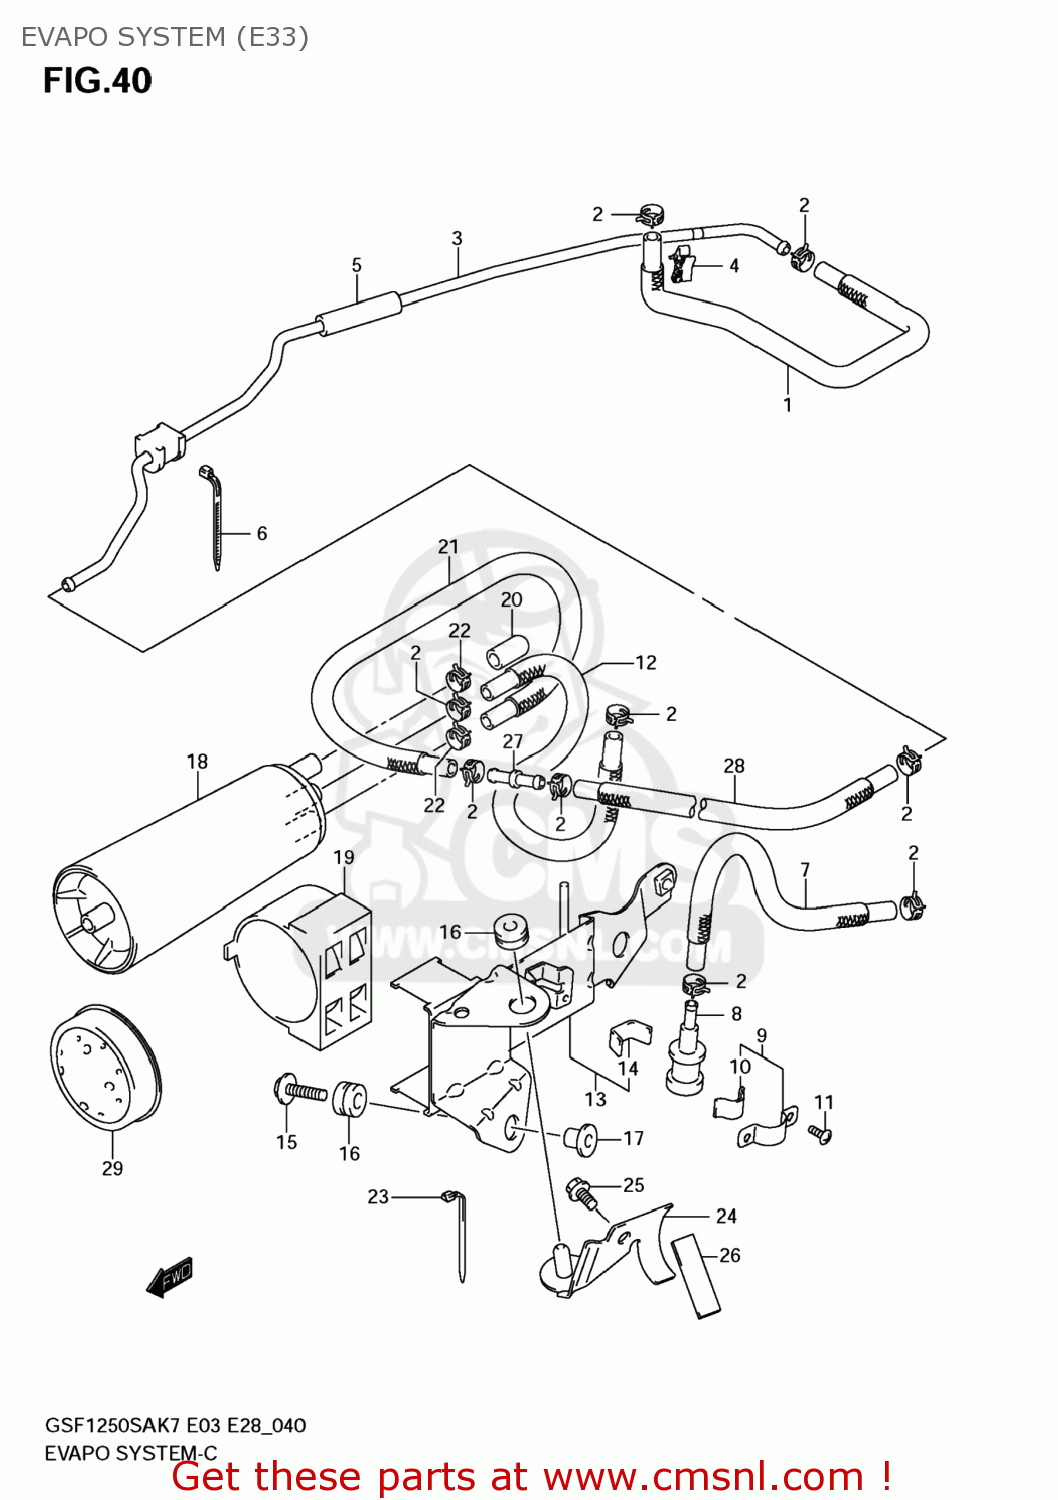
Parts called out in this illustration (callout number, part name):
1	HOSE,TANK & BREATHER VALVE
2	CLIP
3	PIPE,TANK & BREATHER
4	CLAMP
5	CUSHION,FR FENDER SIDE
6	CLAMP(L:95)
7	HOSE,TANK & BRTHR VALVE NO.2
8	VALVE,FUEL TANK BREATHER
9	PLATE,FUEL TANK BREATHER NO.2
10	CUSHION
11	SCREW
12	HOSE,CSTR & BREATHER VALVE
13	BRACKET,CANISTER
14	CUSHION
15	BOLT(6X25)
16	CUSHION
17	WASHER
18	CANISTER ASSY,CHARCOAL
19	CUSHION,CANISTER
20	CAP,OD:11.5
21	HOSE,CSTR & PURGE VALVE
22	CLIP
23	CLAMP
24	BRACKET,EVAP SYSTEM
25	BOLT
26	CUSHION,BRACKET NO.1
27	JOINT
28	HOSE,CSTR & PURGE VALVE NO.2
29	CAP,CANISTER
